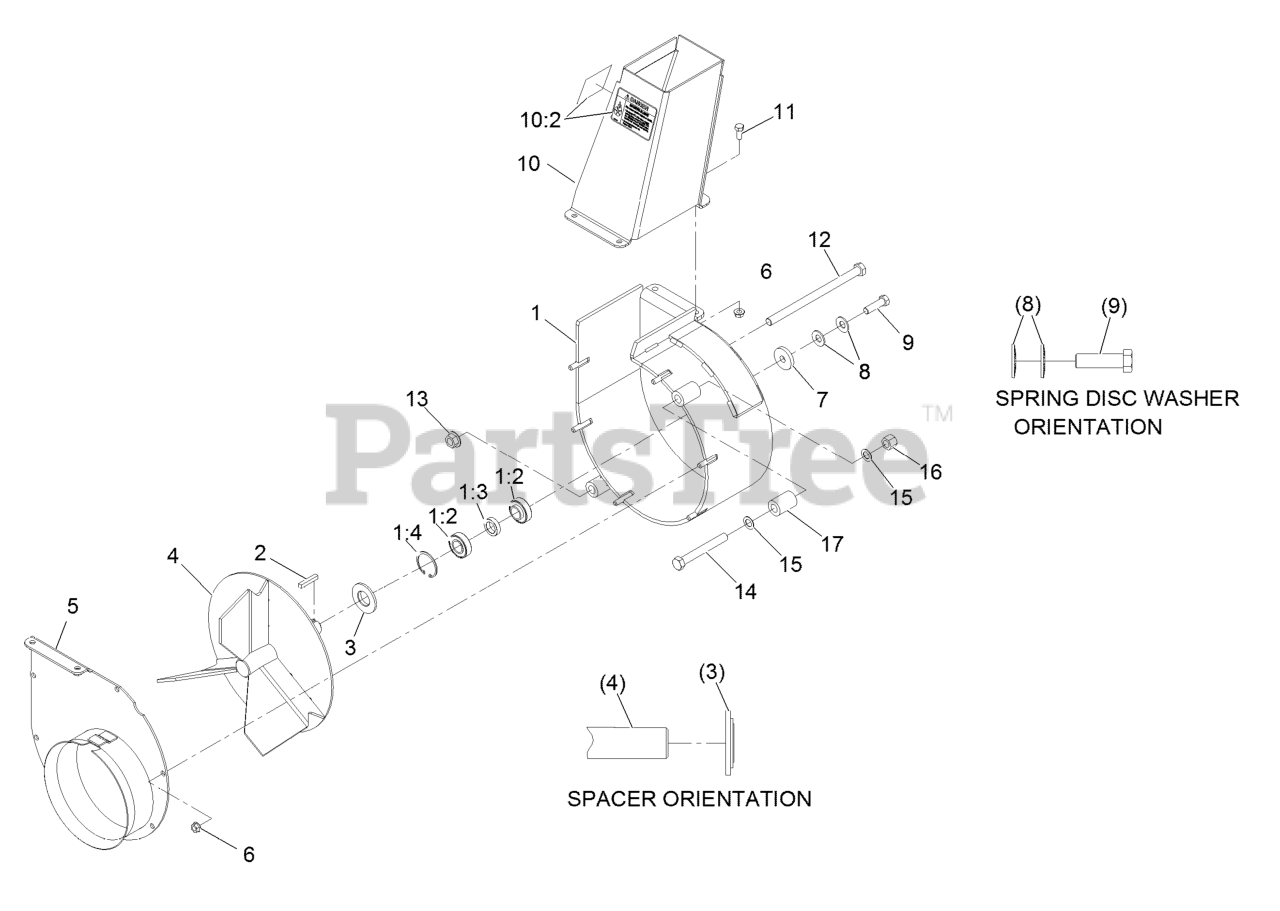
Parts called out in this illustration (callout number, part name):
1	HOUSING ASM
1:2	BEARING-BALL
1:3	SPACER-BEARING
1:4	RING-SNAP
2	KEY-SQUARE
3	SPACER-BLOWER
4	IMPELLER-3 BLADE
5	COVER-BLOWER
7	WASHER-CLUTCH
8	WASHER-SPRING
9	SCREW-HH
10	DISCHARGE CHUTE ASM
10:2	DECAL-DANGER IMPELLER
11	SCREW-HH
12	SCREW-HH
14	SCREW-HH
15	WASHER-THRUST
16	NUT-LOCK, NI
17	SPACER-MOUNT
